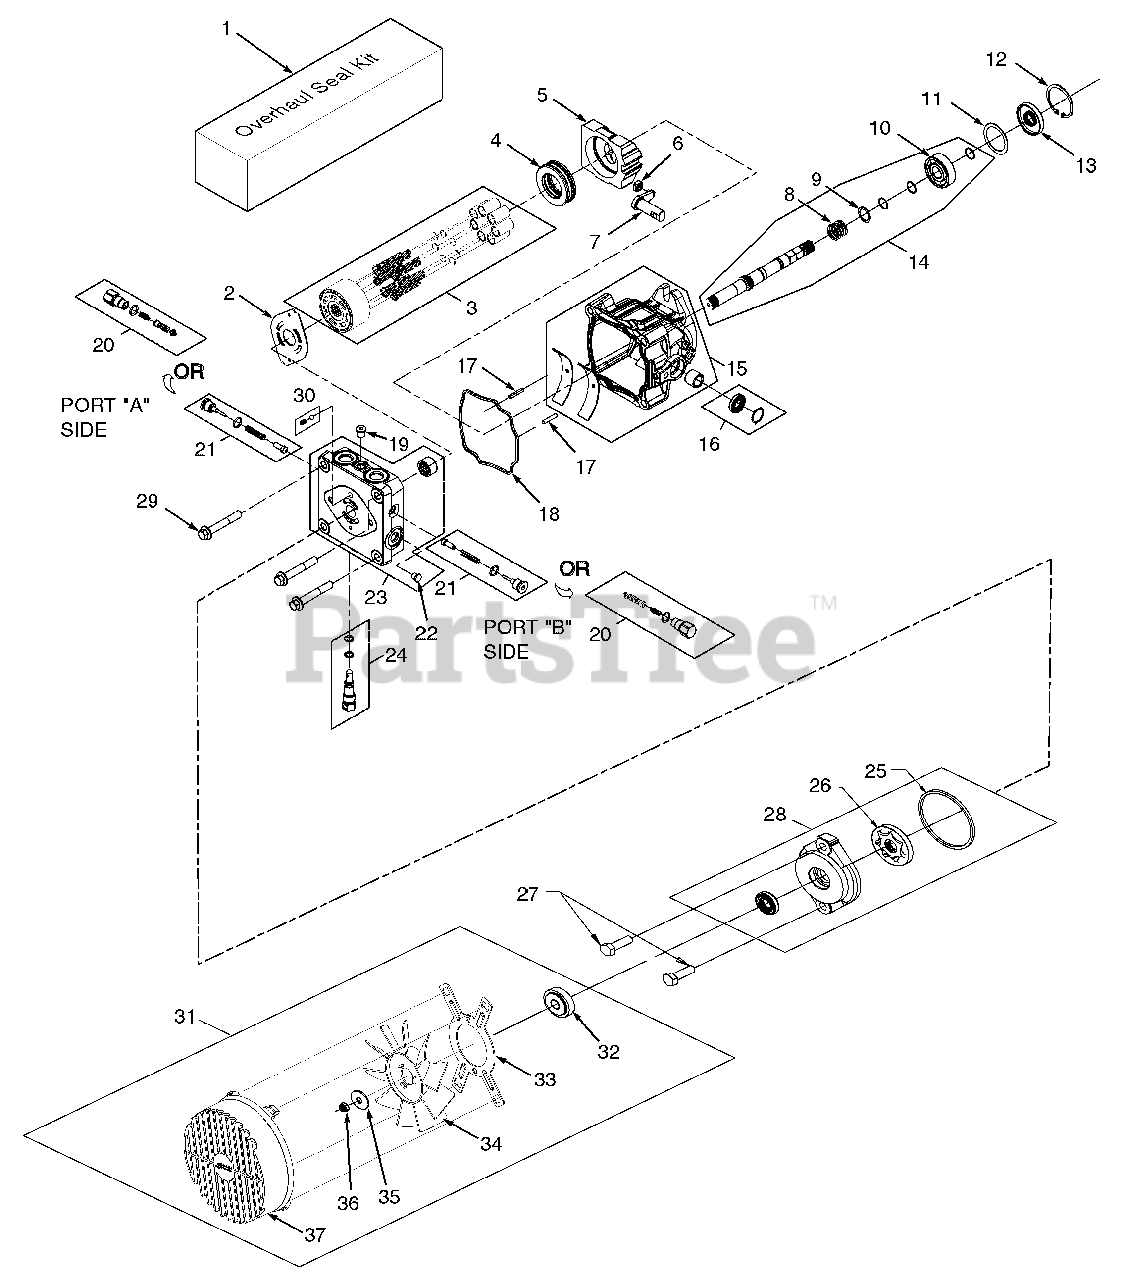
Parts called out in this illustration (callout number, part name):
1	Overhaul Seal Kit
2	Valve Plate
3	Cylinder Block Kit - 16cc
4	Thrust Ball Bearing Assembly
5	Variable Swashplate
6	Slot Guide
7	Trunnion Arm
8	Block Spring
9	Block Thrust Washer
10	Shaft Ball Bearing
12	Retaining Ring
14	Kit, Pump Shaft
15	Housing Kit
16	Trunnion Seal Kit
18	O-Ring
19	Straight Thread Plug
20	Shock Valve Kit
21	Shock Valve Kit
22	Straight Thread Plug
23	End Cap Kit
24	Bypass Valve Kit
26	Gerotor Assembly
27	Socket Head Cap Screw
28	Charge Pump Kit
29	Hex Screw, Flanged Head
30	Charge Relief Kit
31	Fan Kit
33	Bracket, Shroud
35	Washer
37	Shroud
